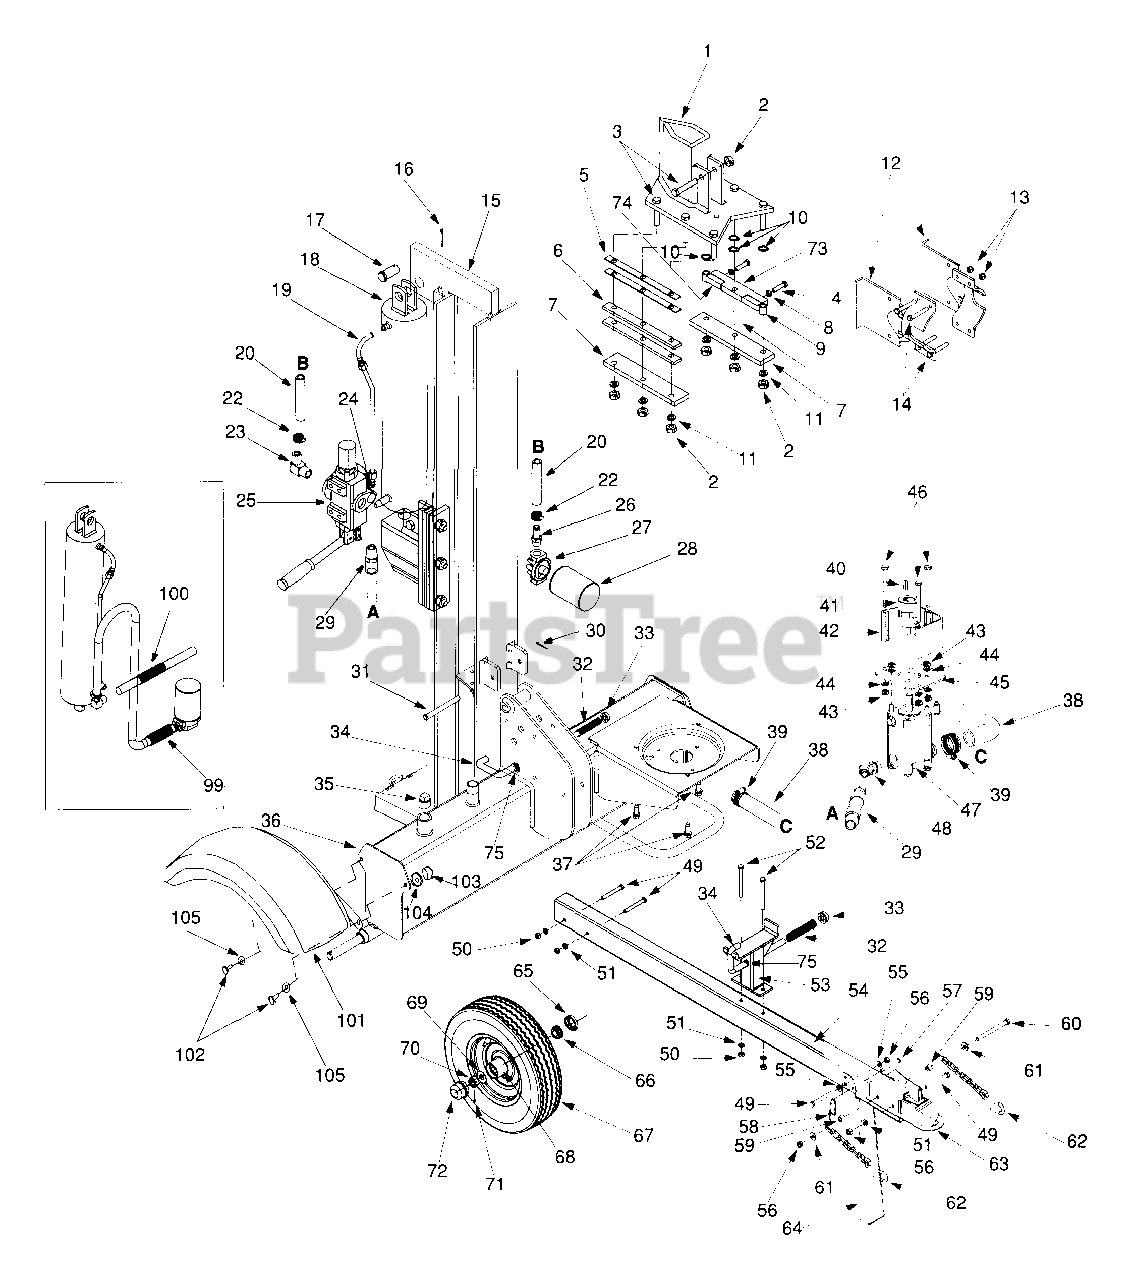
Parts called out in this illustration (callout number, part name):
2	Lock Nut 1/2-20
3	Hex Cap Screw 1/2-20 x 2.75
4	Hex Cap Screw 3/8-24 x 1.5
8	Hex Jam Nut 3/8-24
9	Spacer
10	Flat Washer .531 x .93 x .090
11	Lock Washer 1/2
14	Hex Cap Screw 3/8-16 x 2.5
17	Clevis Pin
20	Return Hose 3/4" I.D. x 44" Lg.
22	Hose Clamp 5/8"
23	Return Elbow
24	90° Solid Male Adapter
26	3/4" Hose Adapter
27	Filter Housing
28	Oil Filter
29	High Pressure Hydraulic Hose
30	Cotter Pin 1/8" Dia.
31	Hinge Pin 1/2 x 4.8" Lg.
32	Comp. Spring 4" Lg.
33	Push Cap
34	Locking Rod
35	Pipe Plug
38	Suction Hose
39	Hose Clamp
40	Sq.-Key 3/16" x .75"
41	Flexible Coupling
42	Coupling Shield
43	Hex Nut 5/16-24
44	L-Wash. 5/16" I.D.
46	Hex Screw 5/16-24 x 3.25
47	Gear Pump (11 GPM)
48	45 Degree Elbow
49	Hex Bolt 3/8-16 x 3" Lg.
50	Hex Nut 3/8-16 Thd.
51	L-Wash. 3/8" I.D.
52	Hex Bolt 3/8-16 x 4" Lg.
55	Flat Washer 3/8
56	Hex L-Nut 3/8-16 Thd.
57	Clevis Pin 5/16 x 2.5" Lg.
58	Spring Pin
59	Spacer 3/8" I.D. x .625" O.D.
60	Hex Bolt 3/8-16 x 4" Lg. (Grd 5)
61	Fl-Wash. 3/8" I.D. x .87" O.D.
62	Chain - Tow Hitch
63	Hitch Coupler
66	Bearing Cone
67	Wheel Asm Comp. - Gray
68	Bearing Cup
69	Fl-Wash..76" I.D. x 1.5" O.D.
70	Slotted Nut 3/4-16 Thd.
71	Cotter Pin 5/32" Dia. x 1-1/4" Lg.
72	Hub Cap
75	Flat Washer .635 ID x .93 OD
99	Hose Guard
100	Hose Guard
103	Hex Nut 5/16-24
104	Lock Washer 5/16
105	Flat Washer 5/16
